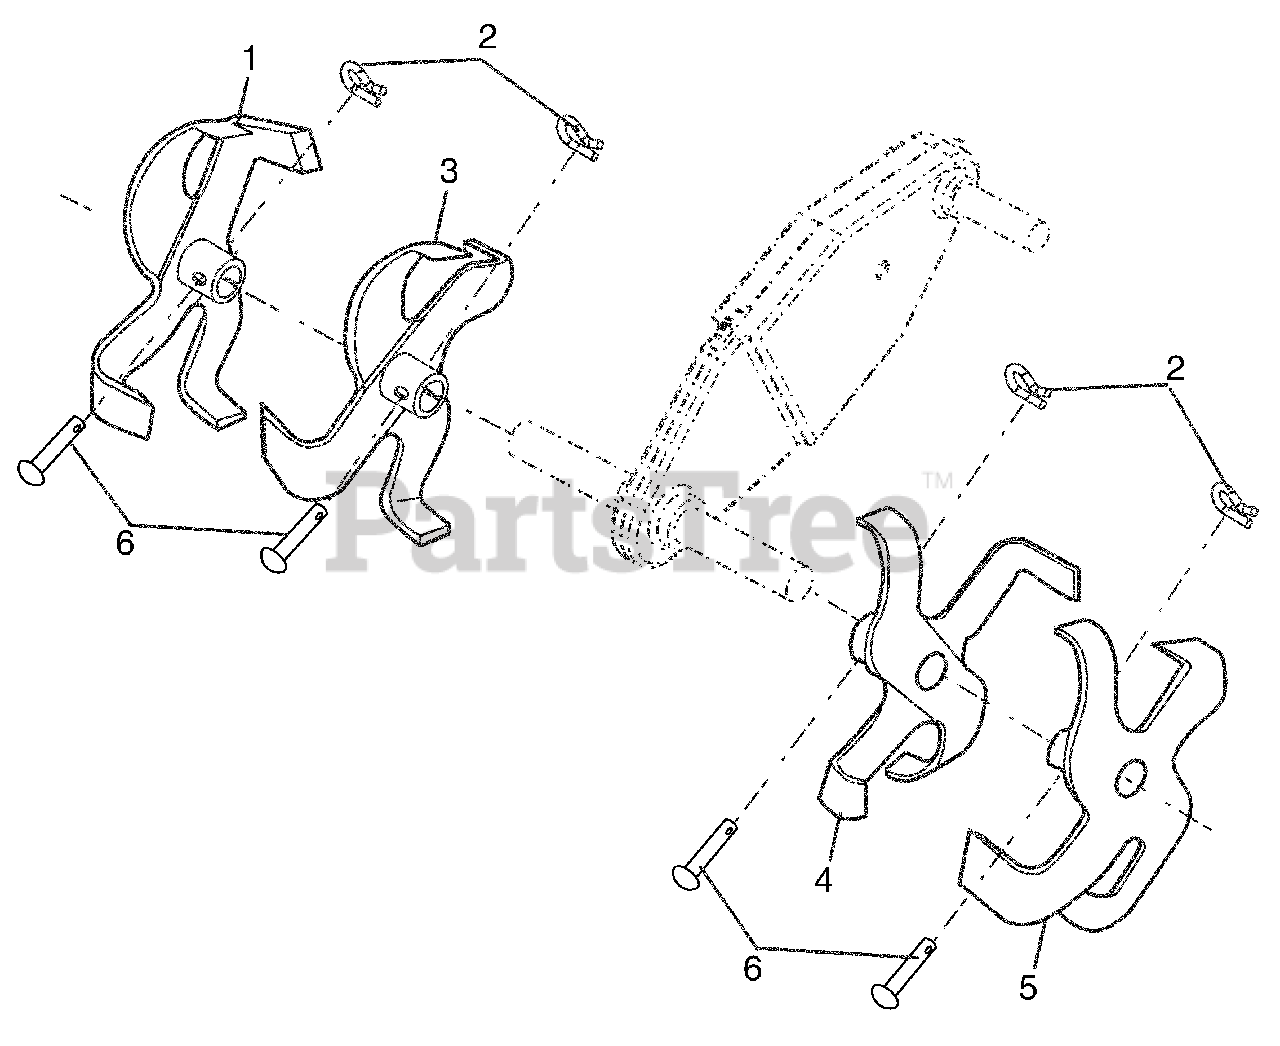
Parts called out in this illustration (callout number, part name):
1	Tine, Outer, R.H.
2	Retainer, Spring
3	Tine, Inner, R.H.
4	Tine, Inner, L.H.
5	Tine, Outer, L.H.
6	Pin, Clevis
